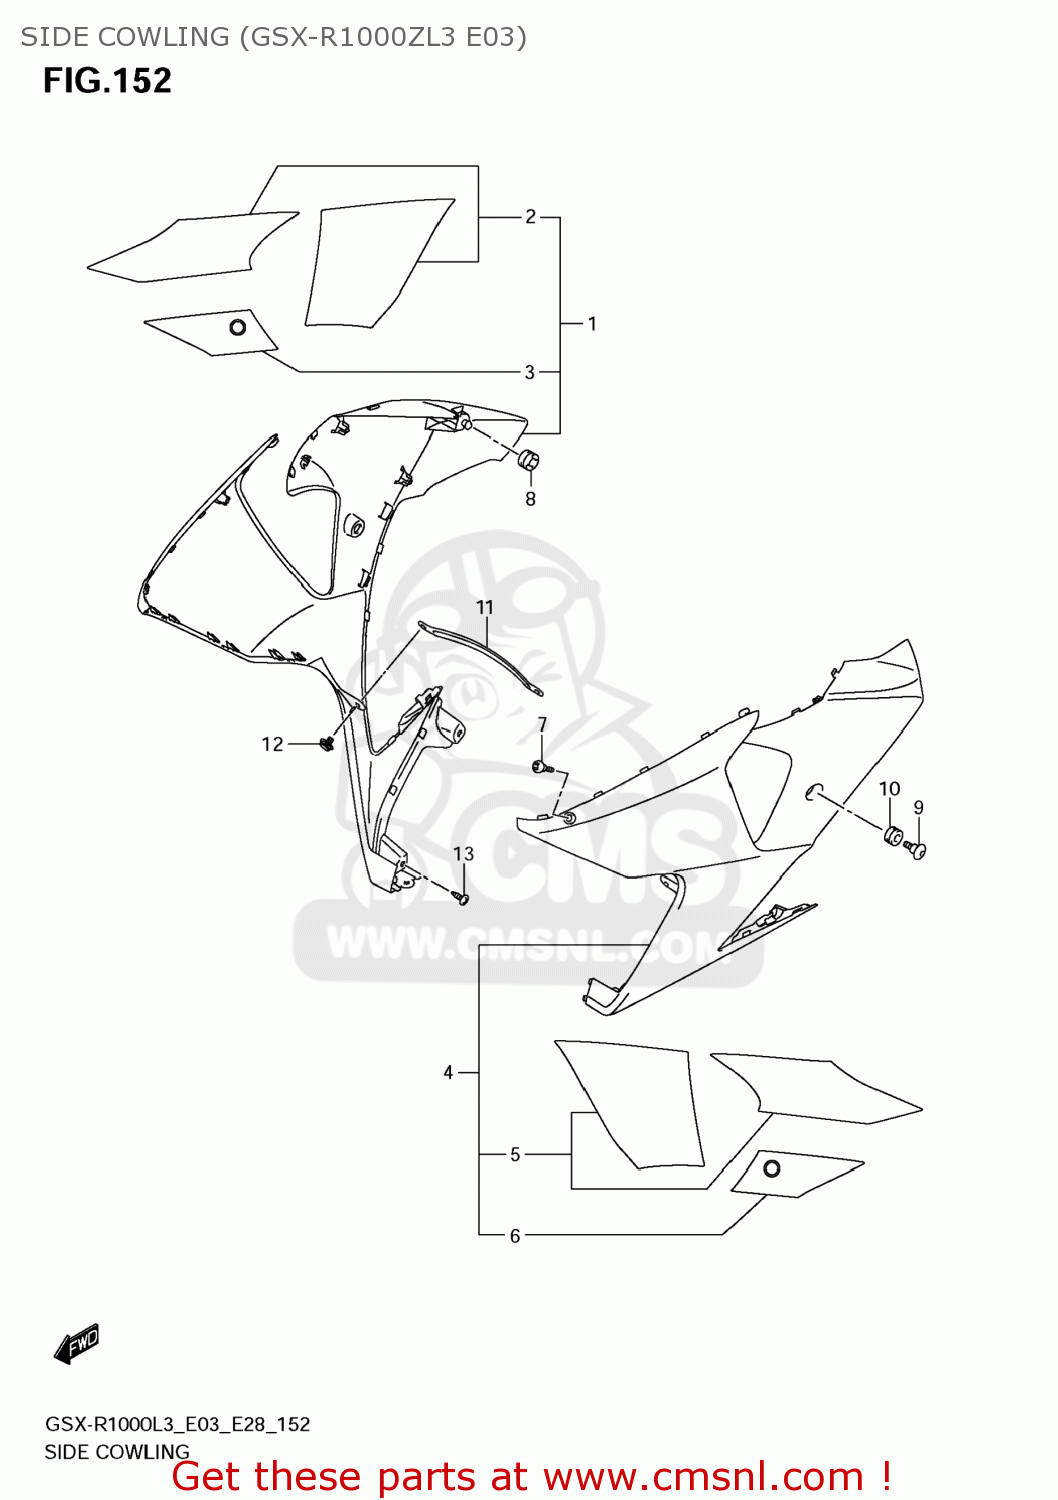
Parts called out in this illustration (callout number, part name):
1	COWLING,SIDE,R(WHITE)
2	TAPE SET,SIDE COWLING,R
3	TAPE,SIDE COWL LWR,R
4	COWLING,SIDE,L(WHITE)
5	TAPE SET,SIDE COWLING,L
6	TAPE,SIDE COWL LWR,L
7	SCREW(5X16)
8	CUSHION
9	BOLT(6X20)
10	CUSHION
11	BRACKET,UNDER COWLING CTR
12	CLIP
13	SCREW
